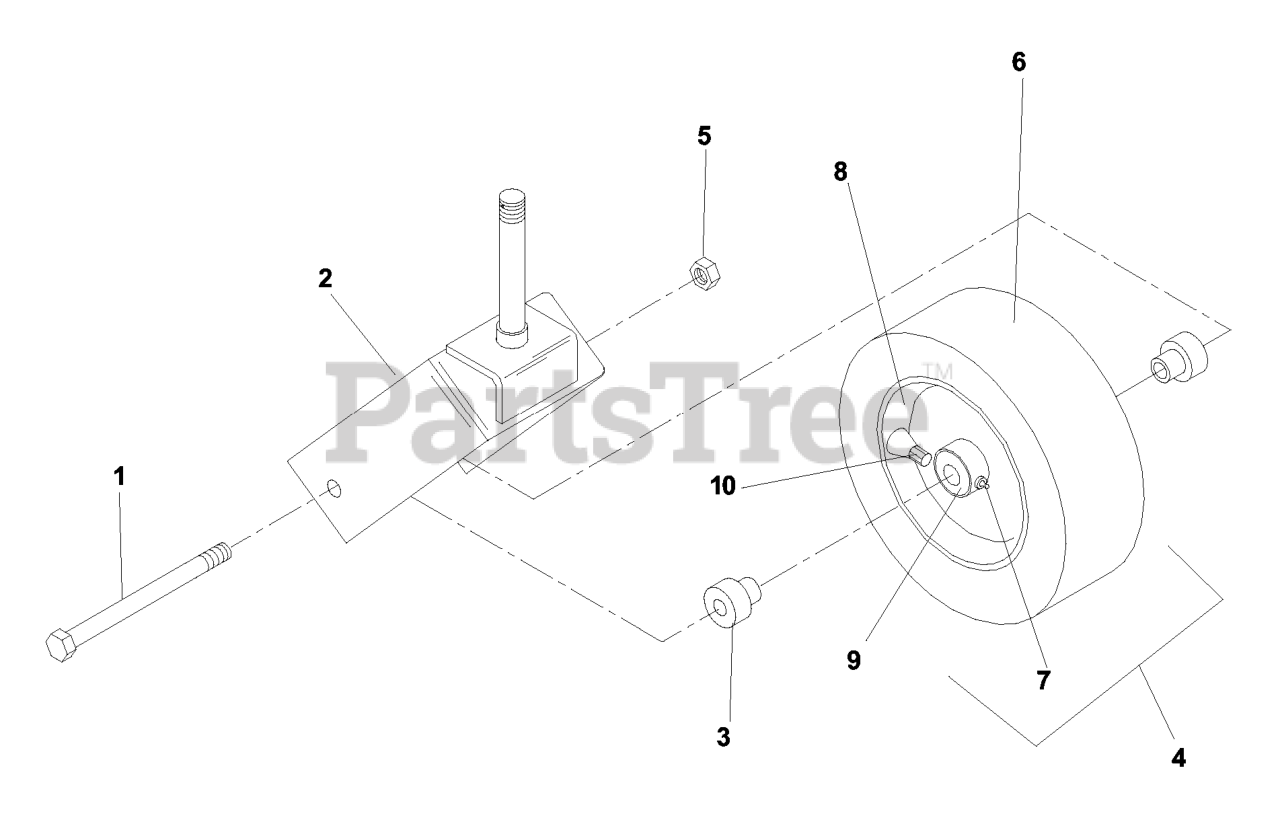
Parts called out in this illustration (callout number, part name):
1	HEX SCREW 1/2-13 X 9.5 GR5
2	CASTOR YOKE ORANGE
3	AXLE SPACER
4	FRONT TIRE ASSY
5	NUT 1/2-13 HEX NYLOC ZD
6	TIRE - SMOOTH 13X6.50-6
7	ZERK
10	VALVE STEM TR-412
